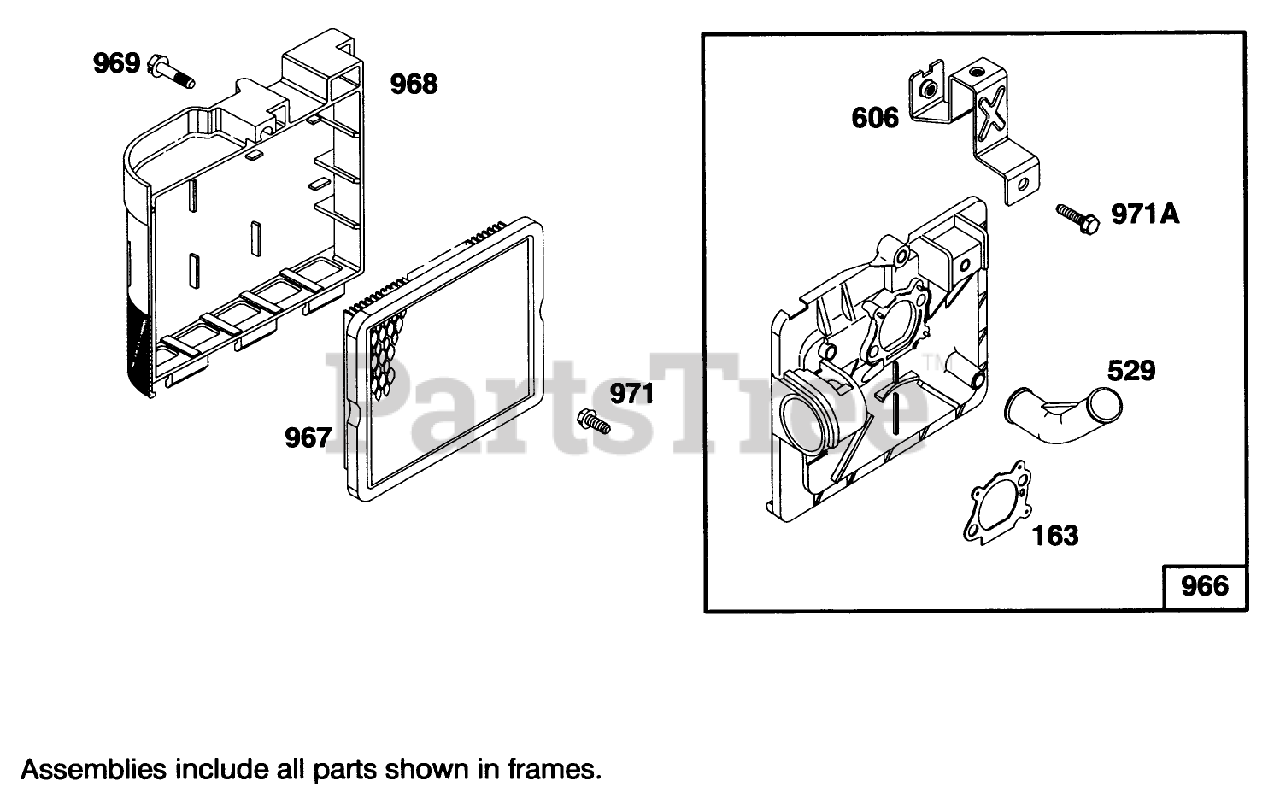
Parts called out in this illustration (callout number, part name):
163	Gasket-Cleaner, Air
529	Grommet
606	Strap-Bracket
966	Base-Primer, Air Cleaner
967	Filter-Air Cleaner, Cartridge
968	Air Cleaner Cover
969	Screw-Cover Mt.
971	Screw-Air Cleaner
971A	Screw-Hex.
